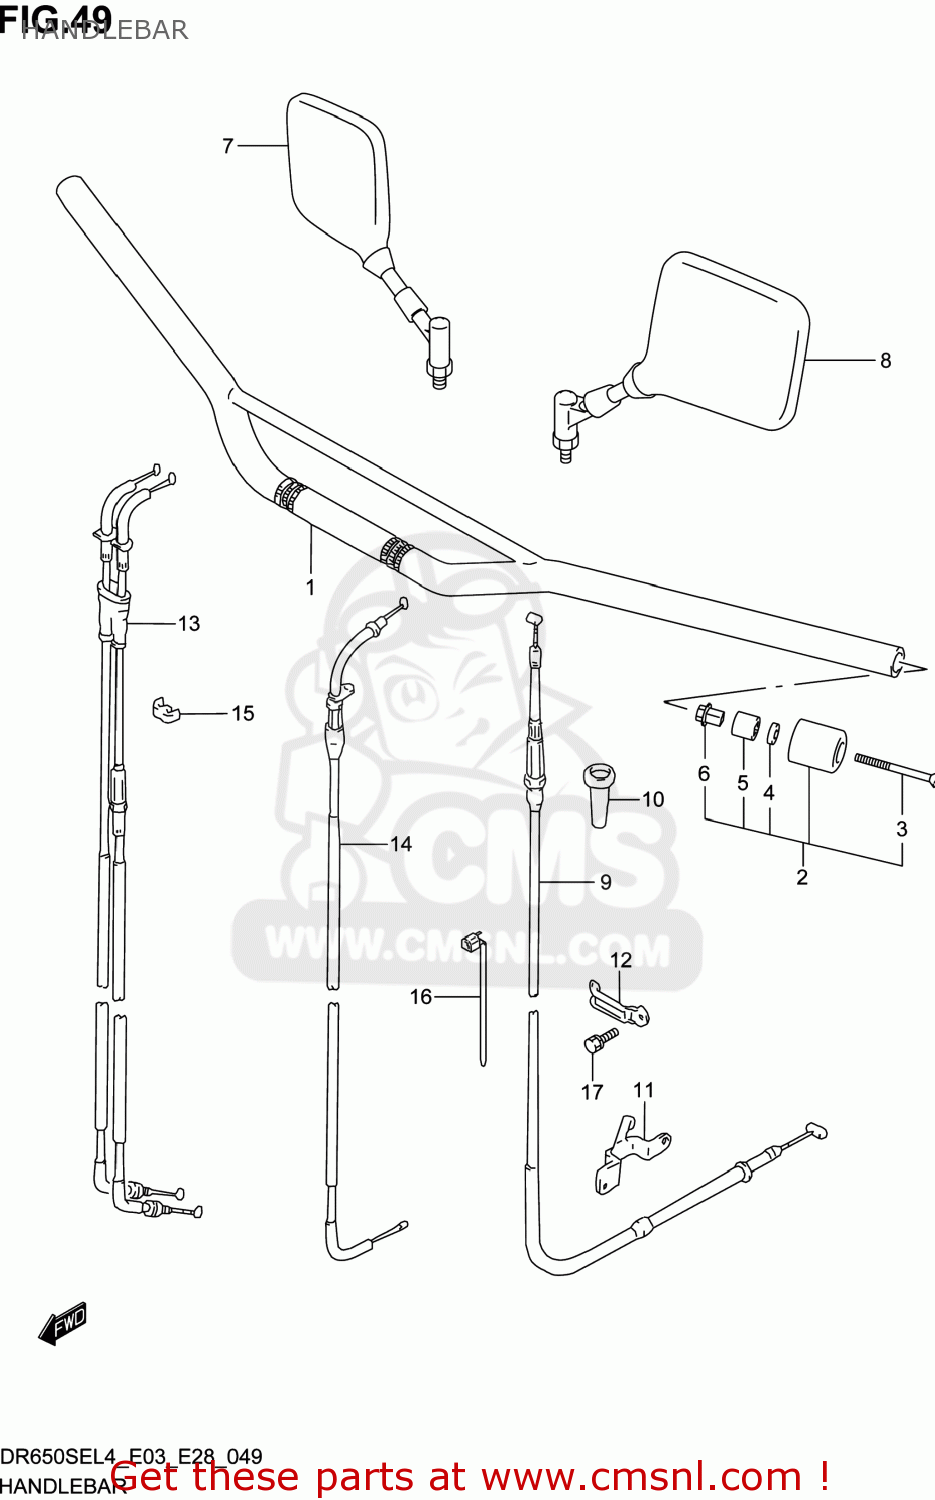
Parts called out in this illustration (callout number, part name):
1	HANDLEBAR(BLACK)
2	BALANCER SET,HANDLEBAR
3	SCREW
4	WASHER(6.5X16X4)
5	EXPANDER,HANDLE BALANCER
6	NUT,HANDLE BALANCER
7	MIRROR ASSY,RR VIEW,R
8	MIRROR ASSY,RR VIEW,L
9	CABLE ASSY,CLUTCH
10	BOOT,CLUTCH CABLE
11	STOPPER,CLUTCH CABLE
12	CLAMP
13	CABLE ASSY,THROTTLE
14	CABLE,STARTER
15	CLIP
16	CLAMP(L:235)
17	BOLT
